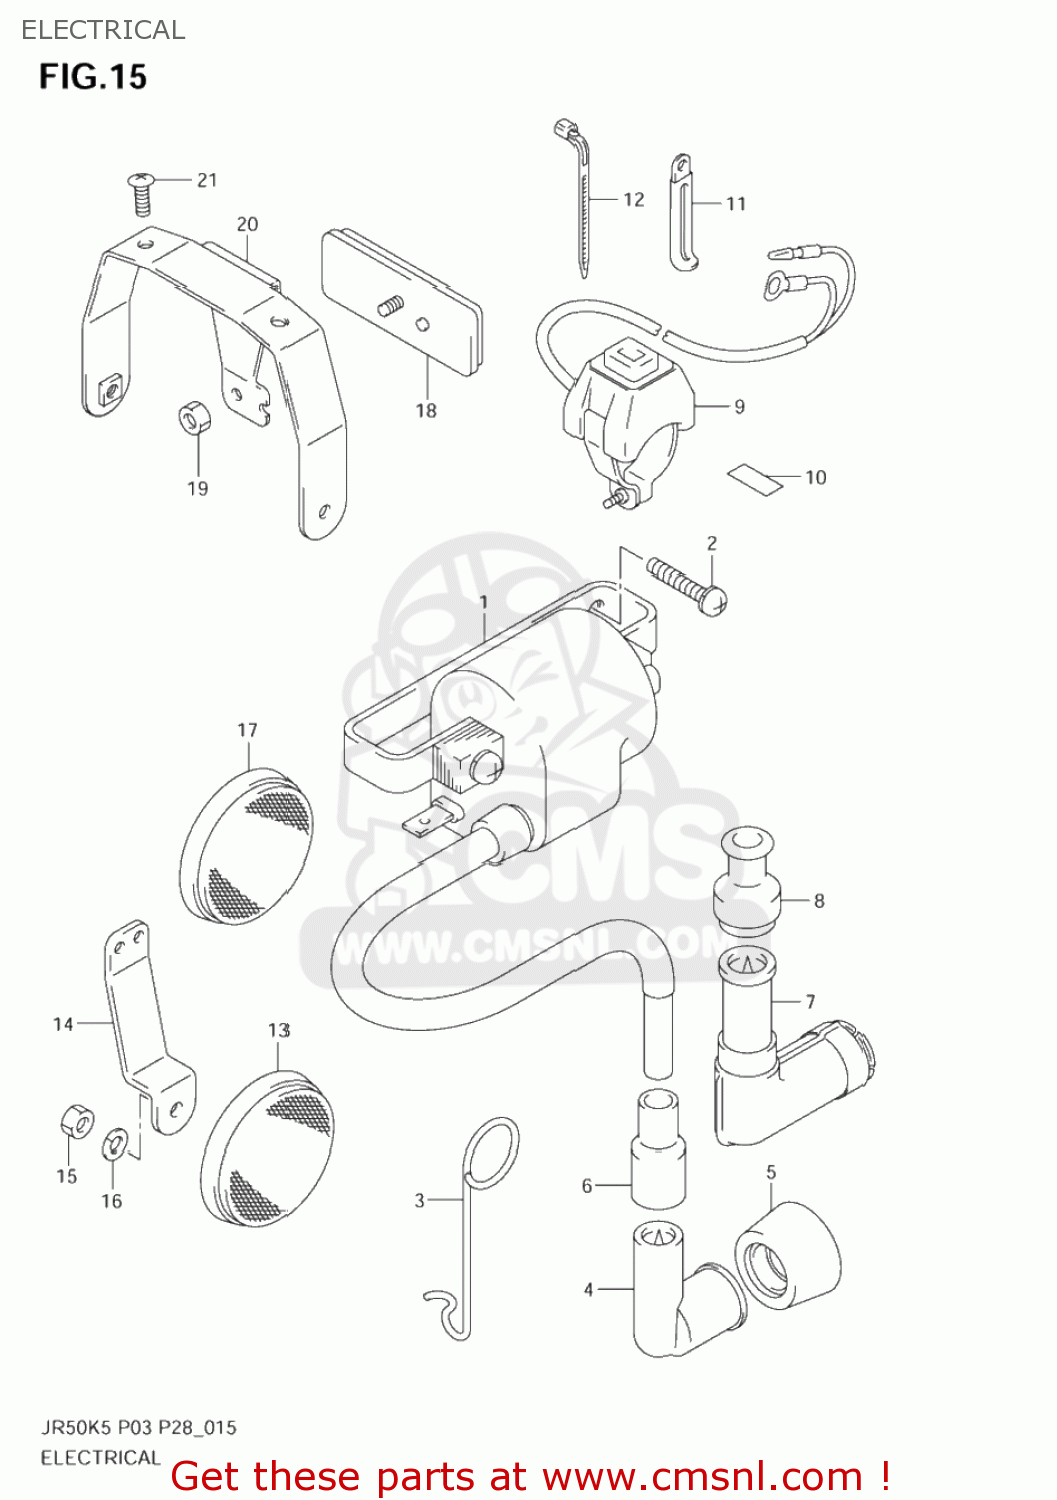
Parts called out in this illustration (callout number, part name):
1	UNIT & COIL ASSY,IGNITION
2	SCREW
3	CLIP
4	CAP ASSY,SPARK PLUG
5	SEAL,SPARK PLUG
6	SEAL,HIGH TENSION CORD
7	CAP ASSY,SPARK PLUG
8	SEAL,HIGH TENSION CORD
9	SWITCH ASSY,ENGINE STOP
10	LABEL,ENGINE STEP SWITCH
11	CLAMP(L:45)
12	CLAMP(L:165)
13	REFLECTOR,REFLEX FR
14	BRACKET,FR SIDE RR
15	NUT
16	LOCK,WASHER
17	REFLEX REFLECTOR,RR
18	REFLECTOR ASSEMBLY,REAR
19	NUT
20	BRACKET,SIDE & RR
21	SCREW 6X12
